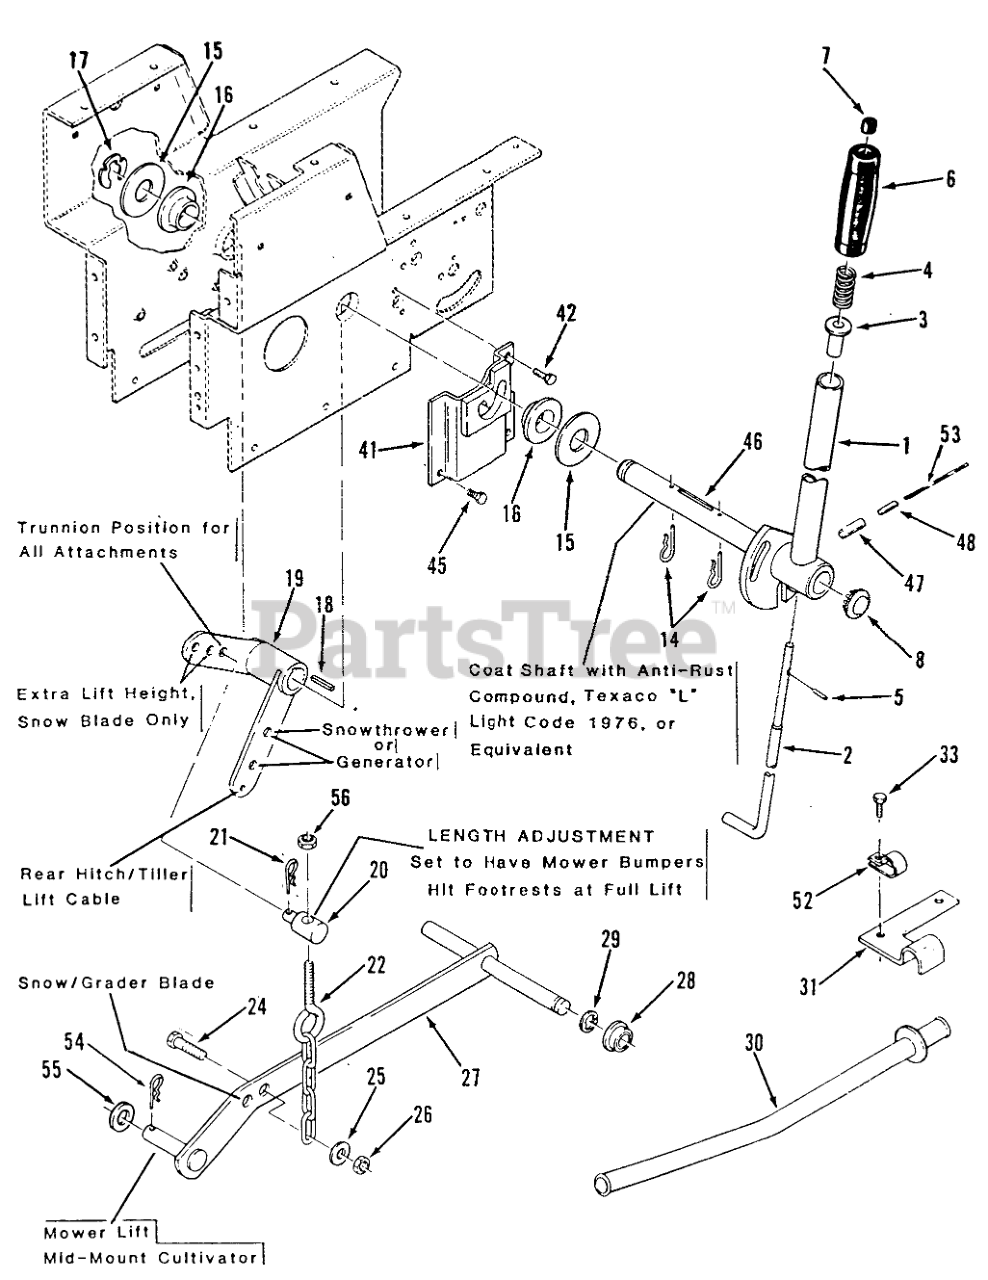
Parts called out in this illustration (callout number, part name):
1	Lift Lever (Includes Items 46, 47, 48)
2	ROD-LATCH LIFT
3	RETAINER-SPRING
4	SPRING-COMPRESSION
5	PIN-SPIROL
6	HANDGRIP
7	CAP-ROD, PLUNGER
8	PLUG
14	Pin-Cotter
15	WASHER
16	BEARING-FLANGE
17	Retainer
18	KEY-SQUARE
19	Bellcrank
20	TRUNNION-LIFT
21	Hairpin
22	CHAIN-LIFT
24	Bolt
25	WASHER 5/16 SAE
26	Nut
27	Bar-Lift
28	BUSHING
29	E Ring
30	TUBE ASSY COMPLET R
31	CLAMP-CONDUIT R
33	BOLT
41	Latch Bracket
42	SCREW
45	Bolt
46	SHAFT-LIFT LEVER
47	SPIROL PIN
48	Roll Pin
52	CLIP
53	Lock Wire
54	Hairpin Cotter
55	Washer
56	NUT
